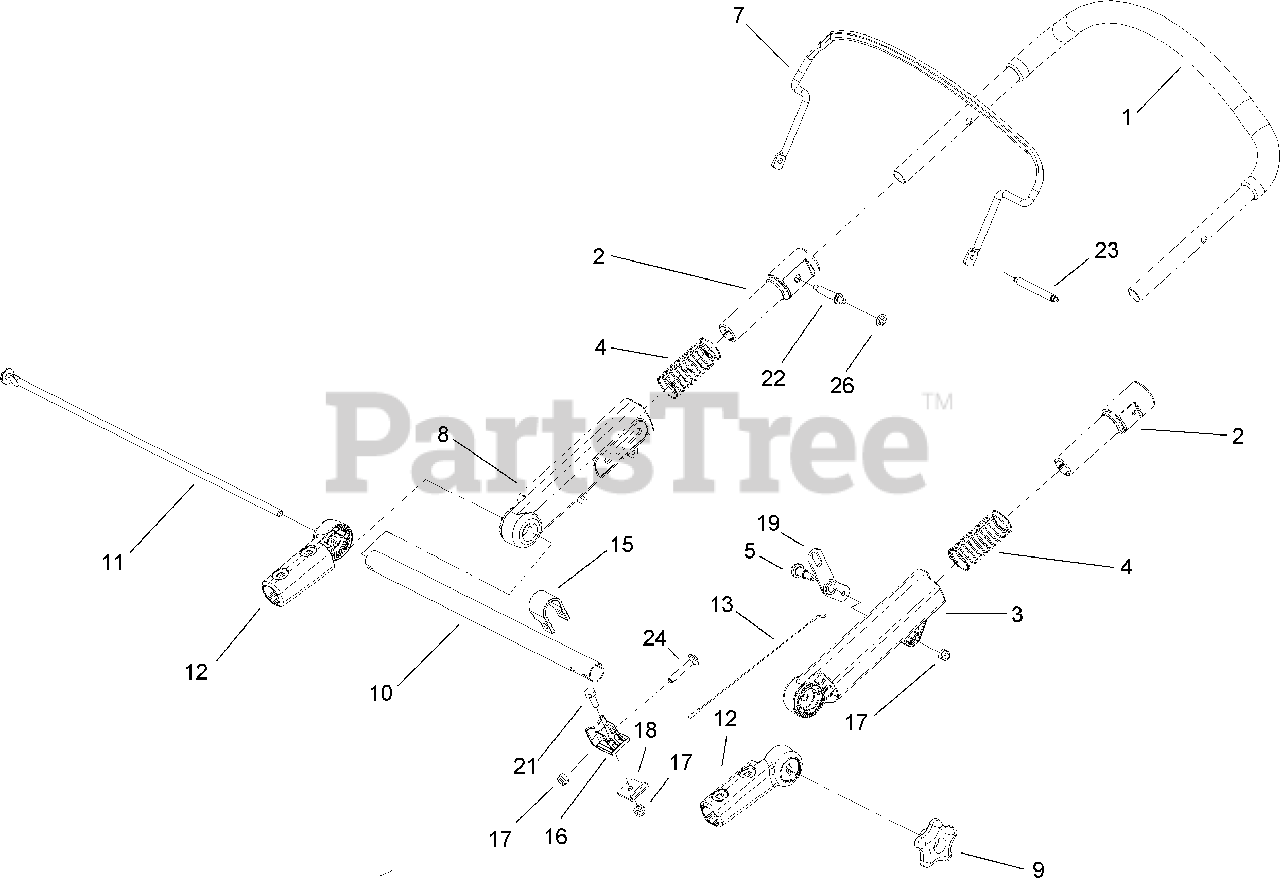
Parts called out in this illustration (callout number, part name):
1	UPPER HANDLE ASM
2	SLEEVE-HANDLE
3	SLIDE-TOP, LH
4	SPRING-COMPRESSION
5	BOLT-SHOULDER
8	SLIDE-TOP, RH
11	ROD-THREADED
12	MOUNT-HANDLE, LOWER
13	CABLE-TRACTION
15	SUPPORT-CABLE
16	SUPPORT-GUIDE, CABLE
17	NUT-LOCK, NI
18	CLAMP-CABLE
19	LEVER-TRACTION
21	SCREW-HH
22	PIN-HANDLE
23	PIN-BAIL, LH
24	SCREW-CARR
26	RETAINER-PUSH ON
